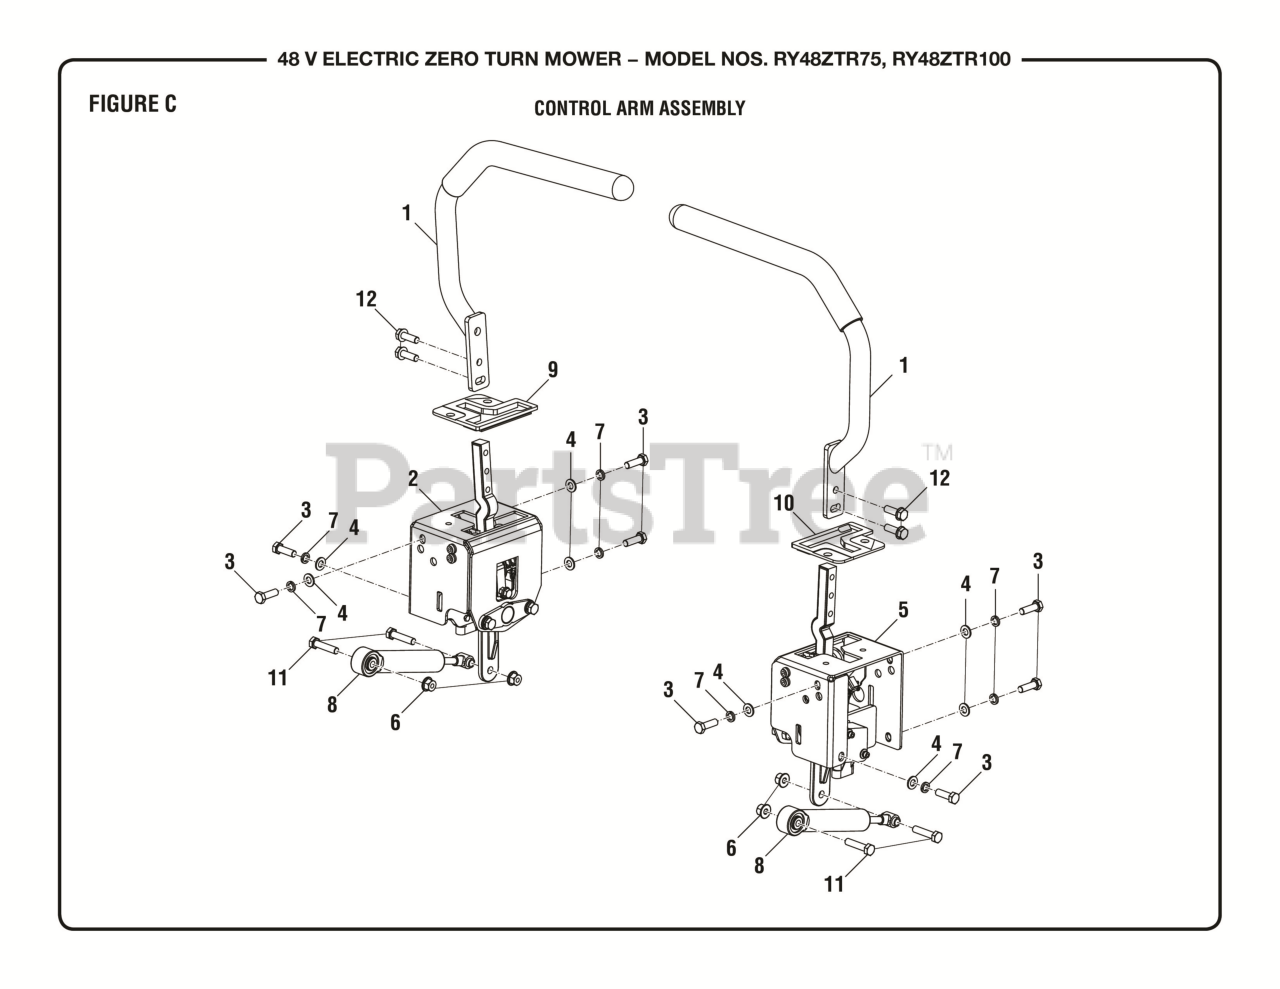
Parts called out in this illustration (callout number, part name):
1	Control Arm Handle
2	Control Arm Assembly, Left
3	Bolt (M8 x 25 mm, Hex Hd.)
4	Washer (OD16 x ID8.4 x 1.6t)
5	Control Arm Assembly, Right
6	Flange Nut (M8) (For Drive Motor Controller V)
7	Lock Washer (OD9.8 x ID8.5 x 5t)
8	Control Arm Damper
9	T Slot Insert, Left
10	T Slot Insert, Right
11	Bolt (M8 x 35 mm, Hex Hd.)
12	Bolt w/Washer (M8 x 25 mm, Hex Hd.)
